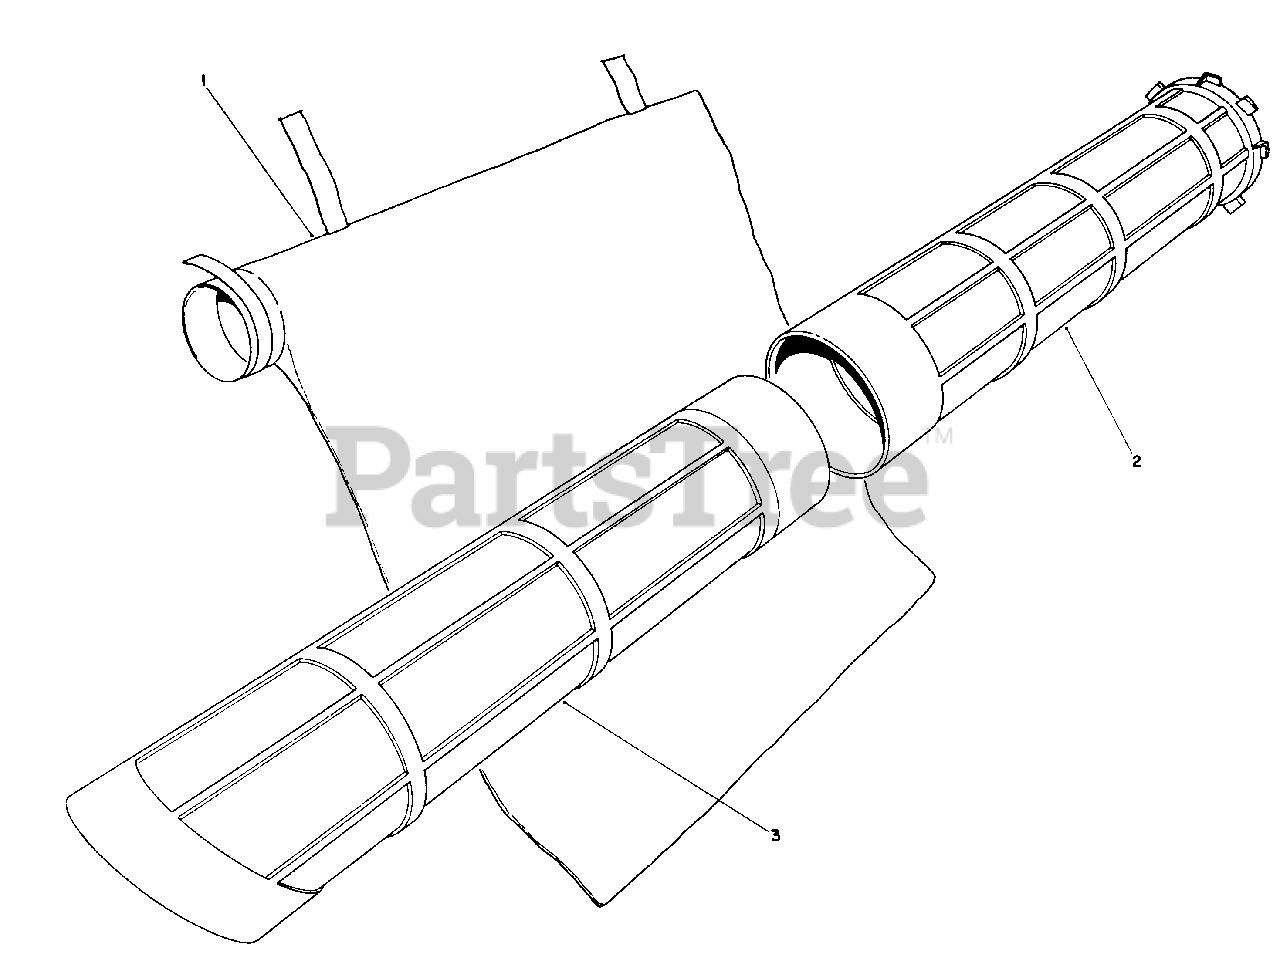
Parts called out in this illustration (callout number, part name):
1	Bag-Vacuum
2	Tube-Vacuum, Upper
3	Tube-Vaccum, Lower
